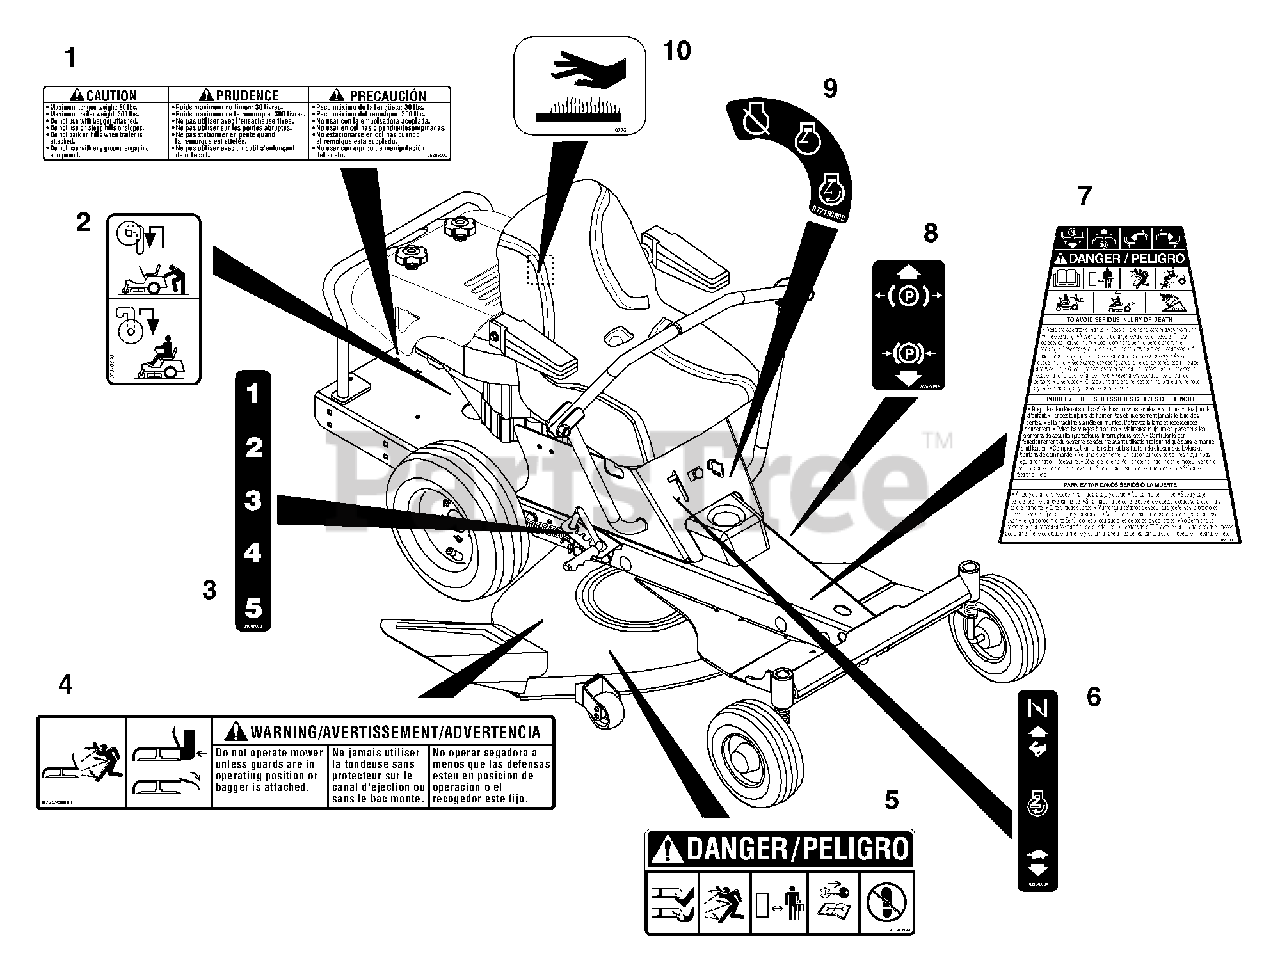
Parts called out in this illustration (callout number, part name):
1	DECAL, TRAILER HITCH
2	DECAL, TRANSMISSION DISCONNECT
3	DECAL-DECK LIFT
4	DECAL, WARNING
5	DECAL, MOWER PAN DANGER
6	DECAL-THROTTLE RER/SPORT
7	DECAL-EZR WARNING
8	DECAL, PARKING BRAKE LEVER
9	DECAL - IGNITION
10	DECAL, HOT SURFACE
